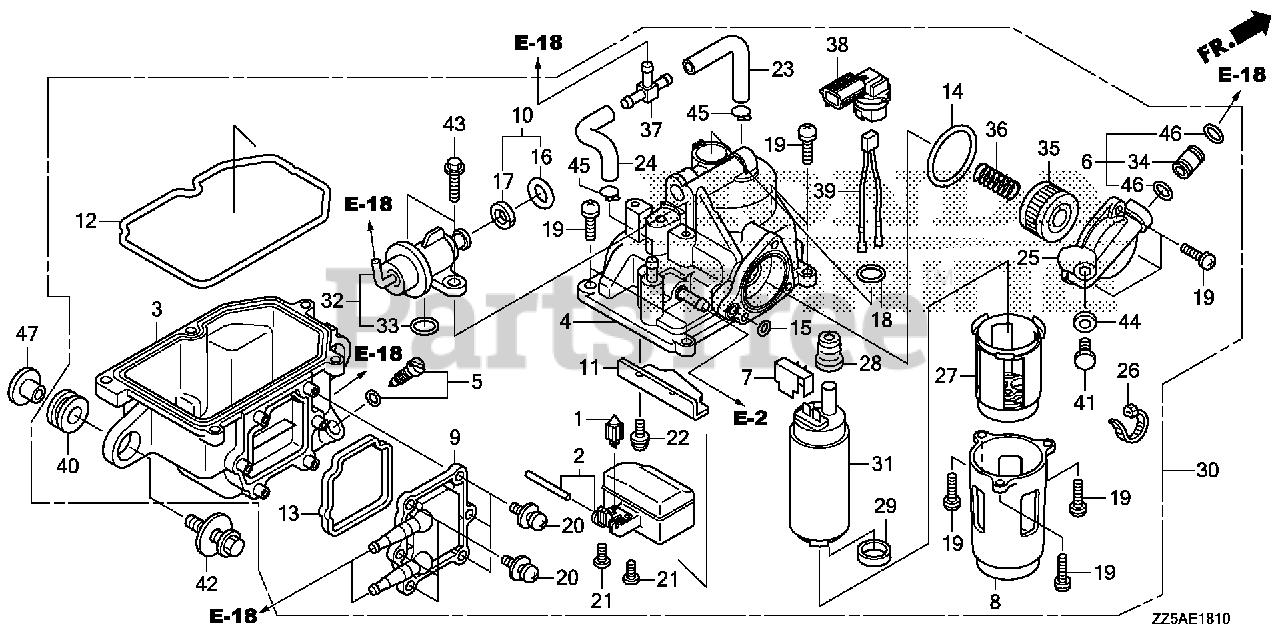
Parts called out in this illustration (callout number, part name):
1	VALVE SET, FLOAT
5	SCREW SET, DRAIN
9	COVER, WATER JACKET
17	RING, BACK-UP
19	SCREW-WASHER
20	SCREW-WASHER
21	SCREW, PAN
22	SCREW, WASHER
23	TUBE A, AIR VENT
24	TUBE B, AIR VENT
28	INSULATOR
30	SEPARATOR ASSY., VAPOR
31	PUMP UNIT, FUEL (MSDS)
32	REGULATOR ASSY., PRESSURE
33	O-RING, PRESSURE REGULATOR
34	JOINT, FUEL PIPE
35	SCREEN, FUEL STRAINER
36	SPRING, COMPRESSION
37	PIPE, THREE WAY JOINT
40	GROMMET, CASE (LOWER)
41	BOLT, SEALING (6MM)
42	BOLT-WASHER (6X25)
43	BOLT, FLANGE (6X14)
44	WASHER, SEALING (6MM)
45	CLIP, TUBE (B10)
46	O-RING (7.8X1.9) (ARAI)
47	COLLAR, MODULE IGNITION CONTROL CASE (CDI)
